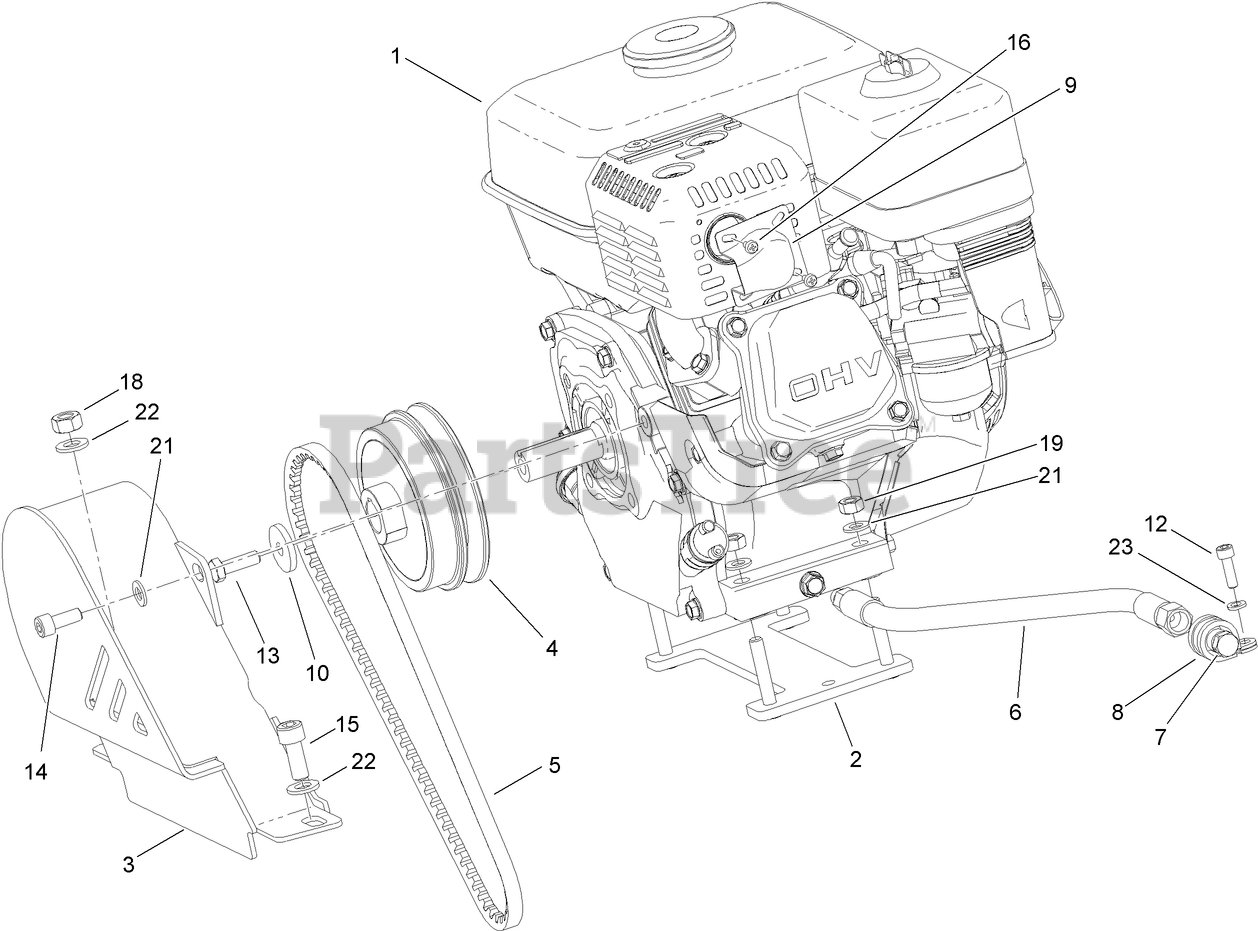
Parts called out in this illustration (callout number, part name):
1	ENGINE-HONDA
2	MOUNT-ENGINE
3	GUARD-BELT
4	PULLEY-DRIVE
5	BELT-V
6	HOSE-DRAIN, OIL
7	PLUG-OIL
8	CLIP-HOSE
9	DEFLECTOR-EXHAUST
10	WASHER
18	NUT-LOCK, NI
21	WASHER
22	WASHER
23	WASHER
